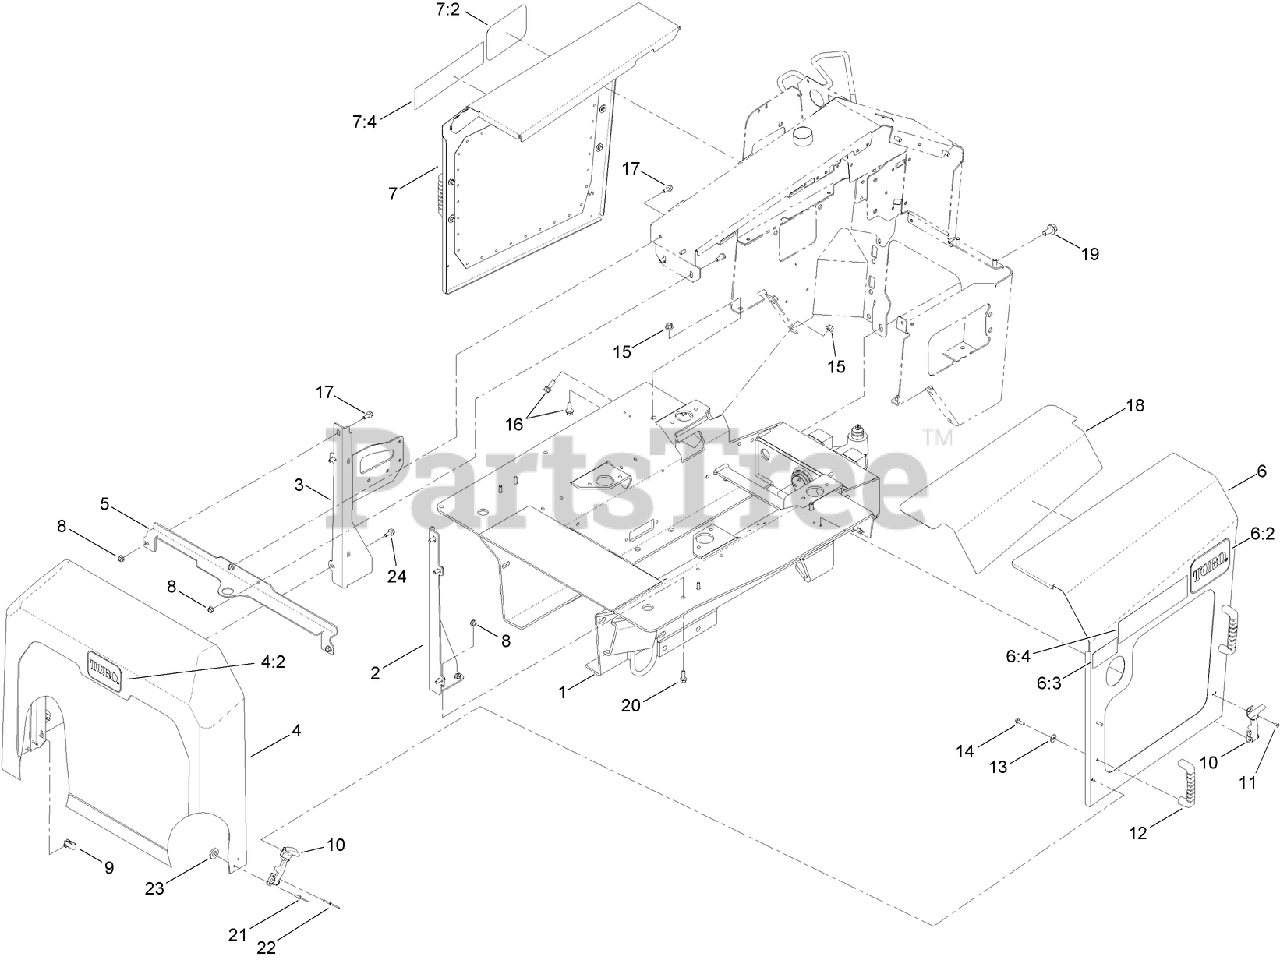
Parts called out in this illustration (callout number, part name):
1	FRONT FRAME AND DECAL ASM
2	BRACKET-COOLER, LH
3	BRACKET-COOLER, RH
4	FRONT COVER ASM
4:2	DECAL
5	BRACKET-COOLING, TOP
6	LH HOOD PANEL ASM
6:2	DECAL
6:3	DECAL-SURFACE, HOT
6:4	DECAL-PRO SNEAK 365
7	RH HOOD PANEL ASM
7:2	DECAL
7:4	DECAL-PRO SNEAK 365
8	NUT-HF, NI
10	LATCH-FLEX, DRAW
12	HANDLE-DOOR
13	WASHER-PLAIN
14	SCREW-HWH
15	NUT-HF
16	SCREW-HHF
17	SCREW-HHF
18	TAPE-HEAT SHIELD
19	SCREW-HHF
20	SCREW-HHF
21	RIVET-POP
22	RIVET-ANNODIZED
23	WASHER-FLAT
24	SCREW-HHF
